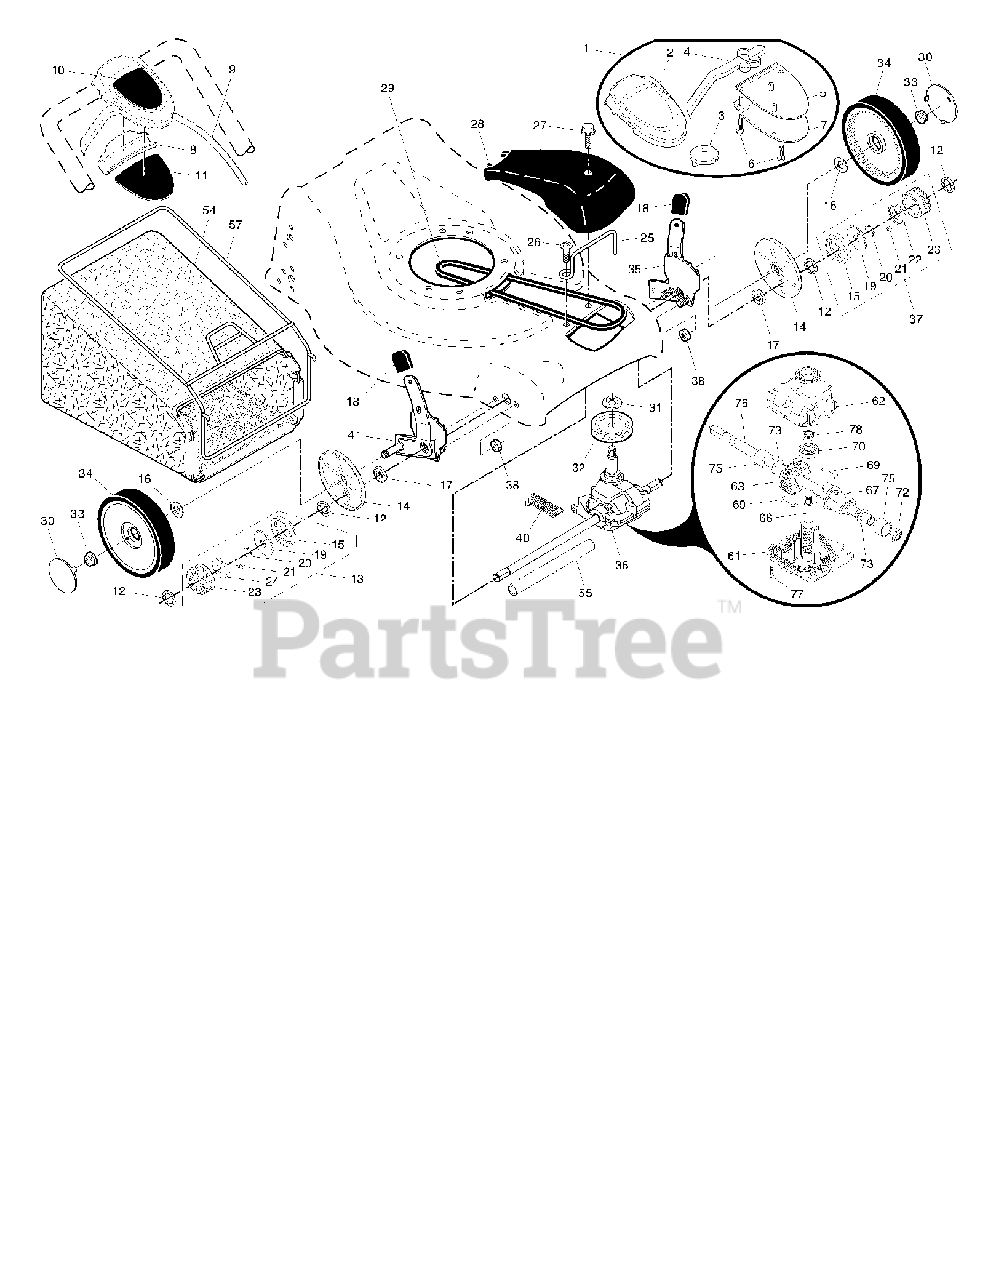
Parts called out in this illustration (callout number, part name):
1	Poulan TBD
3	PULLEY.CAM.DRIVE.CONTROL.HV
4	Lever, Short Marigold
6	SCREW, PHILLIPS HEAD 10 X 5/8
7	BRACKET, DRIVE CONTROL
8	EA WLK COVER PLATE.BLK
10	Poulan TBD
12	E-RING 7/16 RE
13	Pinion Assembly Kit
14	COVER.DUST.WHEEL
15	SEAL.PINION
16	WASHER FLUT
17	BEARING, BALL
18	Knob
19	DISC.DRIVE.21.EZ-WALK
20	SPRING, TORSION
21	PAWL.DRIVE.21.EZ-WALK
22	RETAINER.DRIVE.21.EZ-WALK.LT
23	GEAR, PINION
24	RETAINER, DRIVE, RH
25	KEEPER, BELT
27	SCREW, HEX HD TAPPING #10-24 1
29	V-BELT
31	FLANGED LOCKNUT 3/8-16 ZINC
32	PULLEY
33	Flange Hex Lock Nut, 3/8-16
34	RP.WHEEL.8X2.PR.LP.RAD.BLK
35	KIT.ADJUSTER.ASM.EZ.LH
36	TRANSMISSION.21RD.FGDE
37	PINION ASSY, LH
38	LOCKNUT.NYLOC.1/4-20
40	SPRING, RETURN
41	KIT.ADJUSTER.ASM.EZ(169770).RT
54	Poulan TBD
57	BAG FRAME
61	LOWER CASE
62	UPPER CASE
63	Gear, 27 Teeth
66	SHAFT INPUT (13056)
69	WIRE, FORMED
72	SEAL.OUTPUT.SHAFT
76	SHAFT OUTPUT (12198)
78	SEAL INPUT SHAFT
